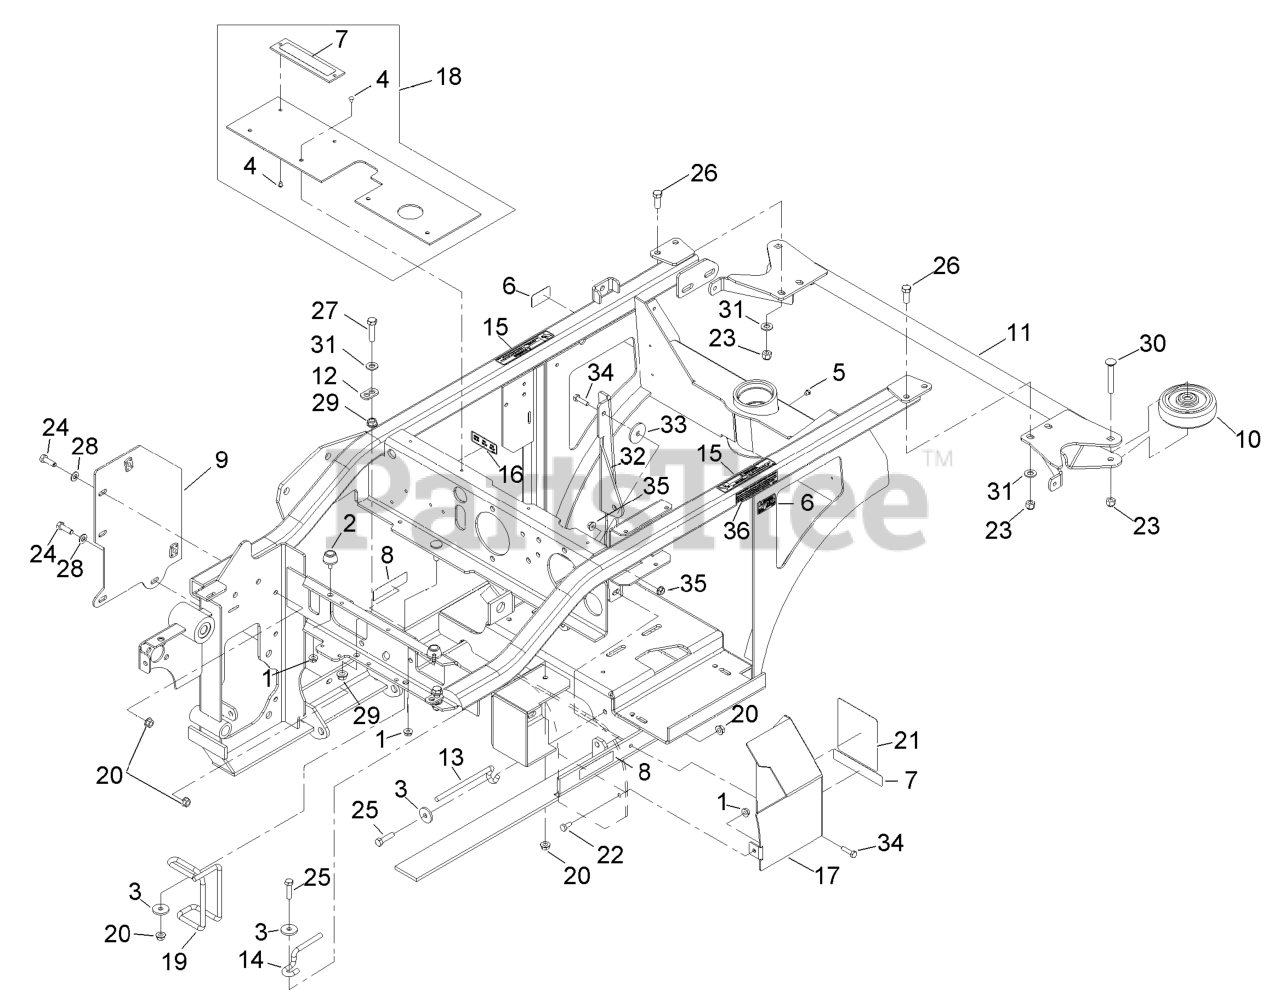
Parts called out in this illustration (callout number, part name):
2	BUMPER-RUBBER
4	RIVET-POP
6	DECAL-SURFACE, HOT
7	DECAL-WARNING
8	DECAL-COVER, MISSING
9	WLD,FENDER (RAW)
10	ROLLER-BUMPER
11	BUMPER-REAR
12	TAB,SPRING ANCHOR
13	GUIDE-BELT
14	GUIDE-BELT
15	DECAL,PINCH POINT
16	DECAL,RELAY
18	LIFT SHIELD ASM
19	GUIDE,BELT (PLATED)
21	DECAL,BELT ROUTING
22	SCREW-HH
23	NUT-LOCK, NI
24	SCREW-HH
25	SCREW-HH
26	SCREW-HH
27	SCREW-HH
28	WASHER-PLAIN
29	NUT-HHF, WHIZ
30	SCREW-CARR
31	WASHER-FLAT
32	BRACE-PTO
34	SCREW-HH
36	DECAL-ARRESTER, SPARK
